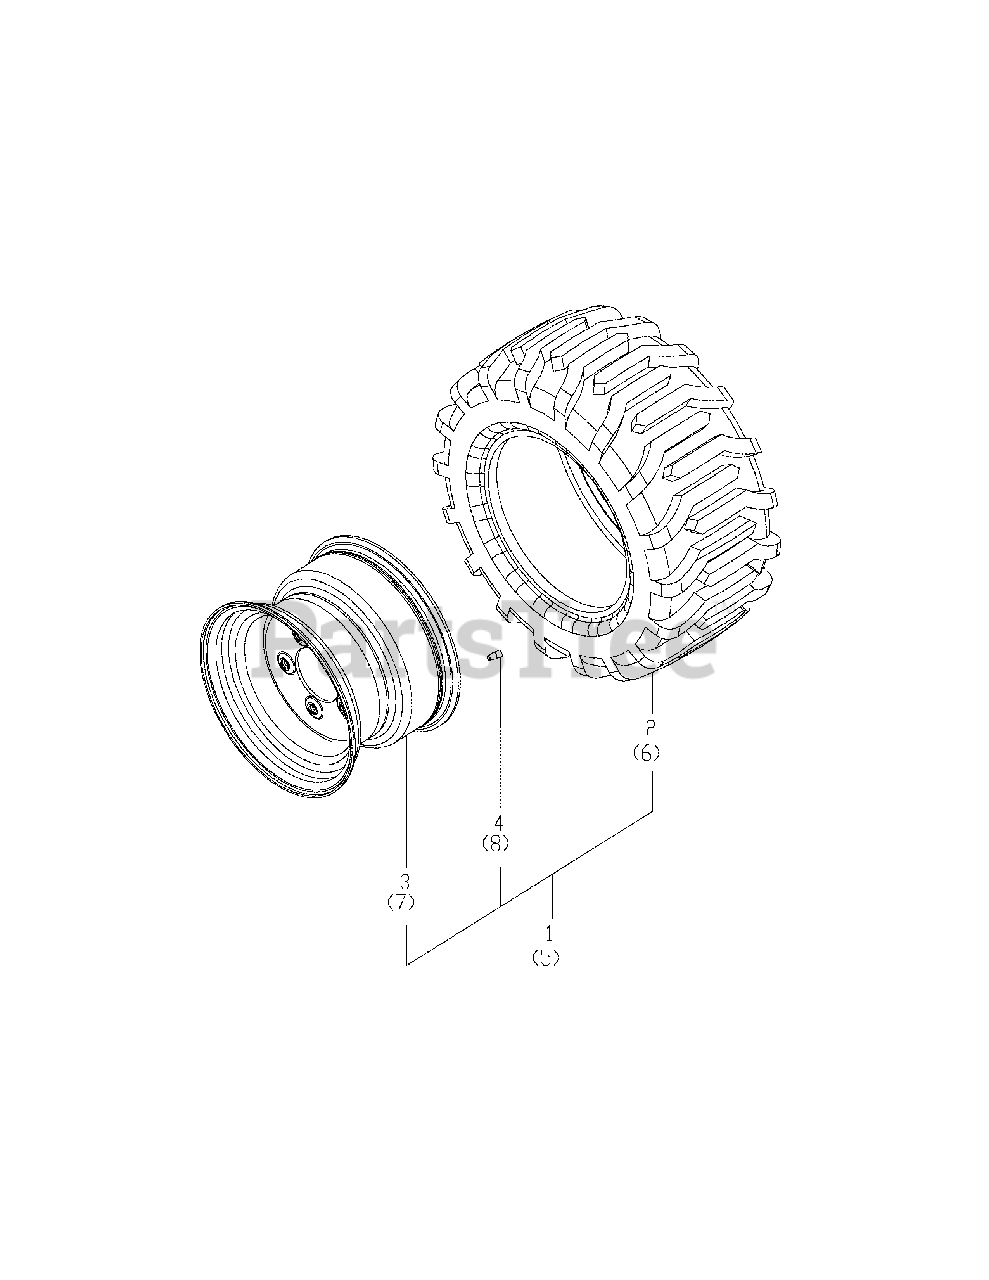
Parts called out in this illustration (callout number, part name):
1	R4 Front Tire L Kit
2	Tire, 18X8.5-10 R4
5	R4 Front Tire L Kit
6	Tire,18X8.5-10 R4
